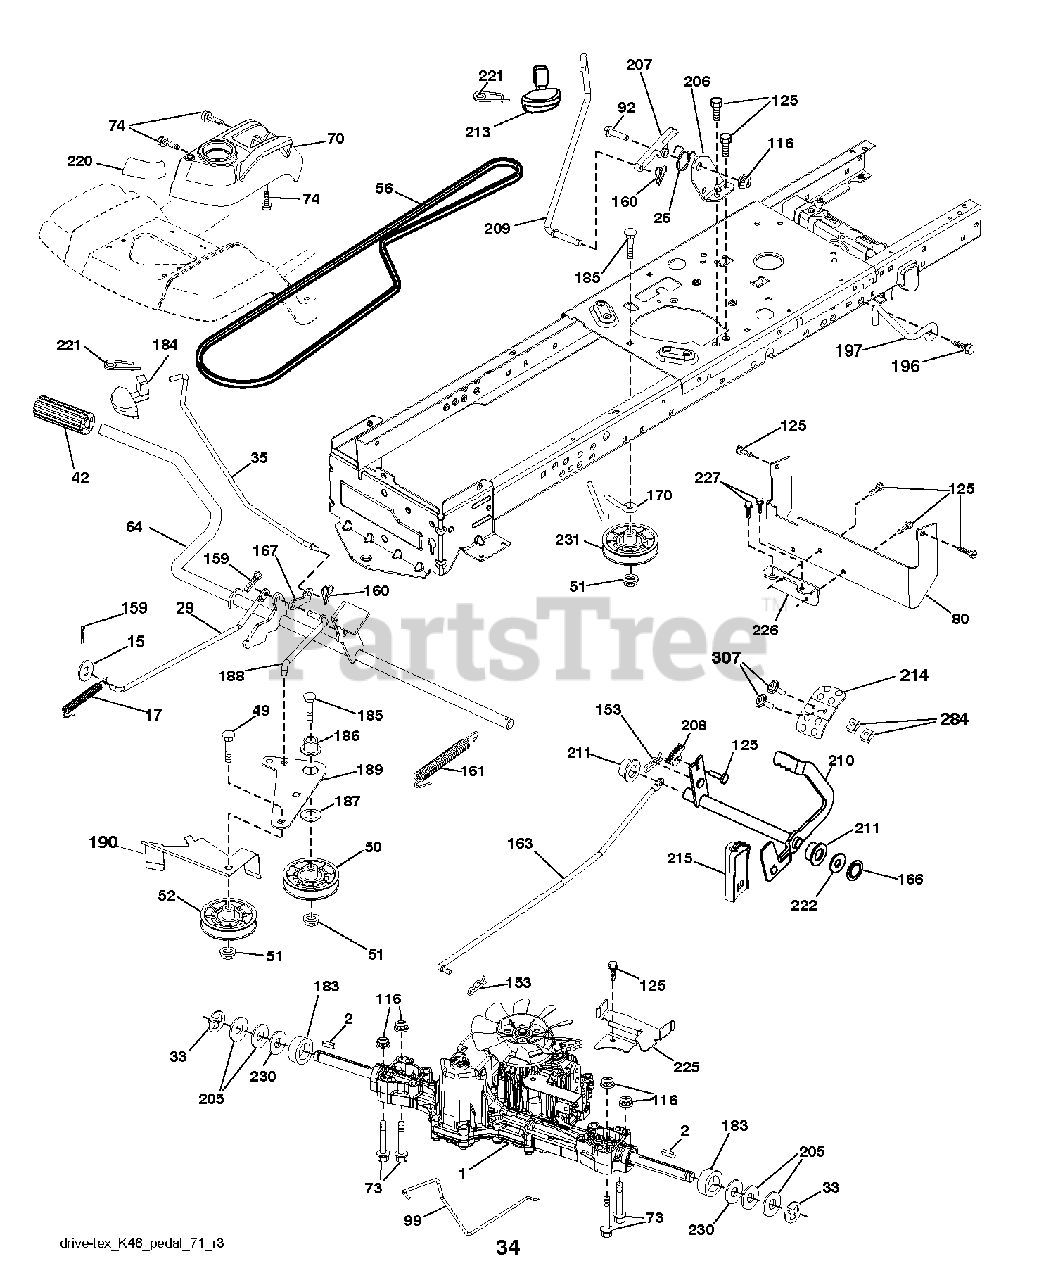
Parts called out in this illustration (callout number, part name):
2	SQUARE KEY
15	WASHER
17	SPRING.BRAKE.K46.GREEN
26	SPRING.RETURN.CRUISE
29	ROD.BRAKE.K46
35	ROD.BRAKE.PARTK.HUSQ.TEX
42	PEDAL COVER T
50	IDLER.FLAT.910.OFFSET
51	NUT LOCK FLG 3/8-16 UNC
52	IDLER.V-GROOVE.910.OFFSET
56	V-BELT.MOWER.92.40.42/K46
64	SHAFT.ASM.PEDAL.BRK.CNTR
70	CONSOLE.ASM.RH.GT.FC.HUSQ
73	BOLT HEX 5/16-18 GR 5
74	SCREW.HI-LO.CONSOLE
80	STRAP.TORQUE.K46.K57R.TT
92	BOLT
99	ROD.SPRING.BYPASS.K46.LT.Z
116	NUT LOCK HEX FLANGE 5/16-18
125	SCREW
153	RETAINER M
159	COTTER PIN
160	RETAINER CLIP
161	SPRING, RETURN LT
163	ROD.CONTROL.PEDAL.K46
166	NUT.PUSH.625
167	LATCH.BRAKE.SPRING
170	KEEPER.CENTER SPAN.1.688
183	SPACER AXLE
184	RB HANDLE.PARKG.BRK.HUS/PRED
186	SPACER.RETAINER
187	WASHER 12/32X2X10GA
188	RP LINK.CLUTCH.GROUND.DRIVE
189	BELLCRANK.GROUND.DRIVE.TEX.
190	KEEPER.BELLCRANK.DRIVE
196	SCREW 3/8-16X1
197	LINK.CLUTCH.ANIT-ROTAT
206	BRKT.MOUNT.LATCH.CRUIS
207	LATCH.CONTROL.CRUISE
208	GEAR.SECTOR.CONTROL.CR
209	ROD.CONTROL.CRUISE.GT.
210	ROCKER.ASM.PEDAL.CONTR
211	BEARING.NYLON
213	KNOB.CONTROL.CRUSIE.HU
214	PEDAL.FORWARD.HUSQVARNA.DEALER
215	PEDAL.REVERSE.TEX.GT.4
220	REFLECTOR.RH.TEX GT
221	RETAINER.SPRING.CLIP.H
222	WASHER 21/32 X 1-1/4 X 10 GA.
225	KEEPER.BELT.TRANSAXLE.K46
226	BRACKET.MOUNT.TORQUE.K46.TLT
227	SCREW
230	WASHER.HARDENED
231	IDLER.V-GROOVE.1.688.OFFSET
284	NUT.U-CHNL.1/4-20.550DP.350PNL
307	SCREW.MACHINE.CR.1/4-20
